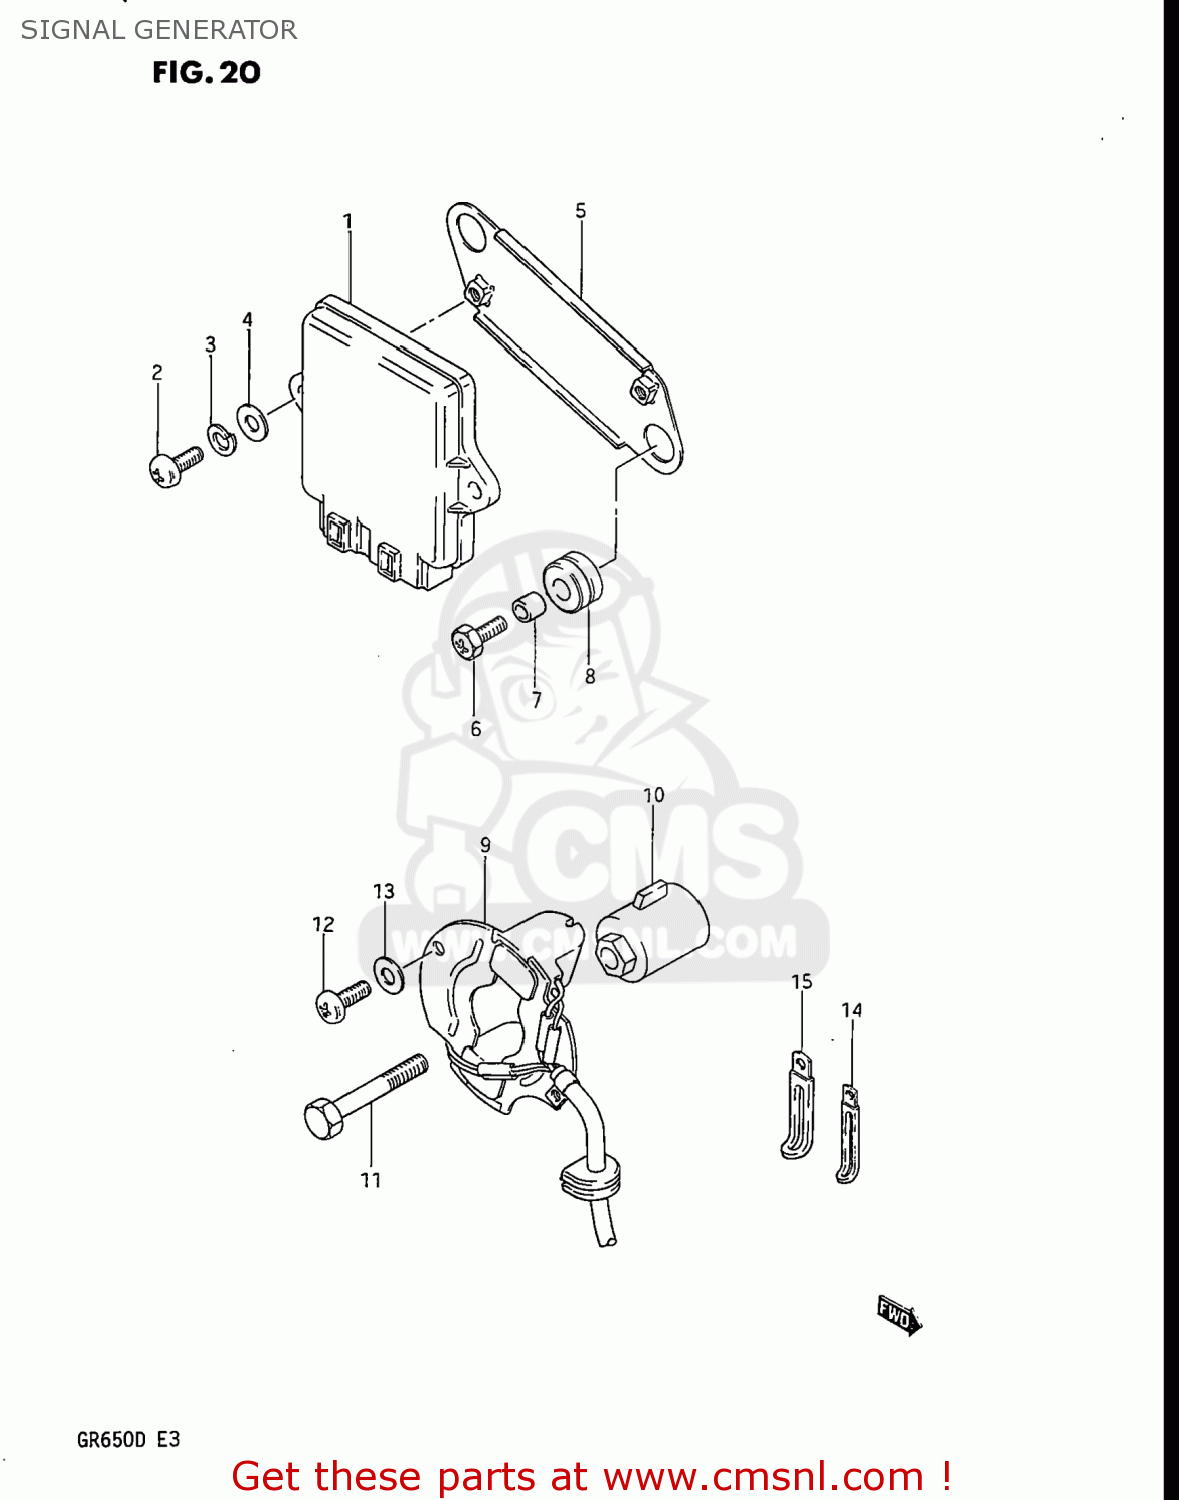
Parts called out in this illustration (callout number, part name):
1	IGNITER UNIT ASSEMBLY
2	SCREW
3	LOCK WASHER
4	WASHER
5	BRACKET,IGNITER
6	SCREW
7	SPACER(6.2X8.3X6.1)
8	CUSHION
9	SIGNAL GENERATOR ASSEMBLY
10	GOVERNOR ASSEMBLY
11	BOLT 8X50
12	SCREW(5X12)
13	WASHER
14	CLAMP L:35
15	CLAMP
